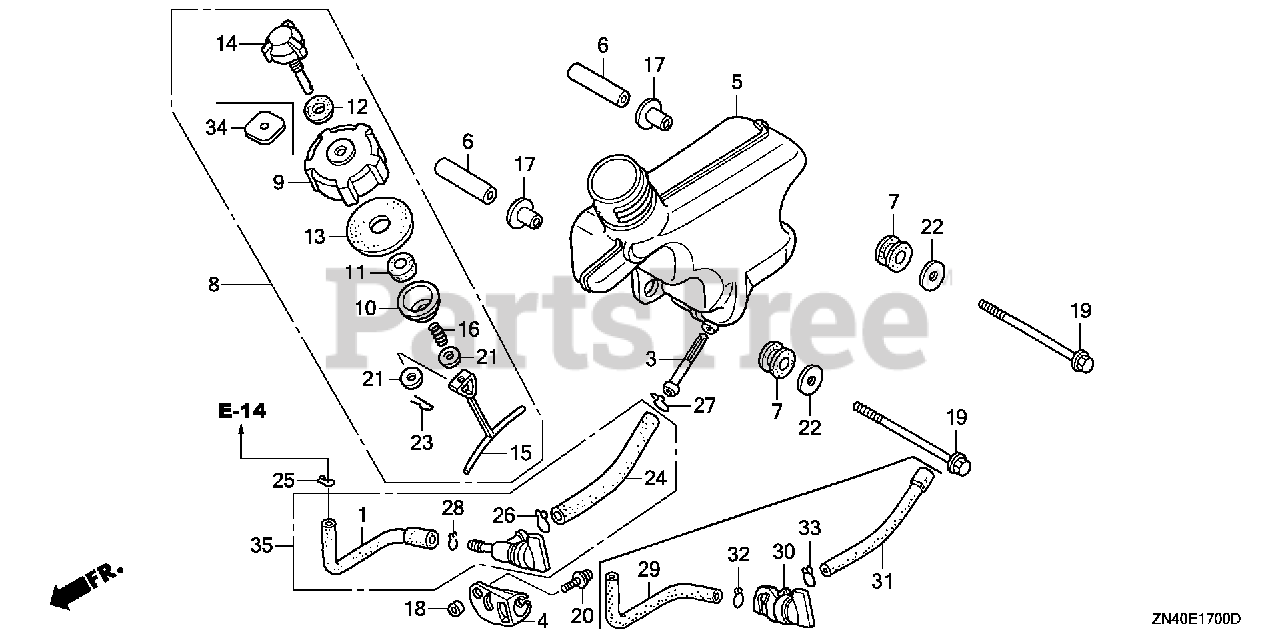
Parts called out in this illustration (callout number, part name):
3	FILTER, FUEL
5	TANK, FUEL
6	COLLAR, TANK SETTING
7	RUBBER A, TANK MOUNTING
8	CAP ASSY., FUEL TANK
9	BODY, FUEL CAP
10	INNER, FUEL CAP
11	SPONGE, FUEL CAP BREATHER
12	GASKET, VALVE
13	GASKET, FUEL CAP
14	VALVE, BREATHER
15	LINK, FUEL CAP
16	SPRING, FUEL CAP
17	COLLAR, CANISTER MOUNTING
18	COLLAR, FR. TURN SIGNAL
19	BOLT, FLANGE (6X65)
20	SCREW-WASHER (5X10)
21	WASHER, PLAIN (4MM)
22	WASHER, PLAIN (6MM)
23	PIN, LOCK (4MM)
25	CLIP, TUBE (B8)
27	CLIP, TUBE (B12.5)
29	TUBE B, FUEL
30	PETCOCK ASSY.
31	TUBE, FUEL TANK
32	CLIP, TUBE (B8)
33	CLIP, TUBE (B10)
